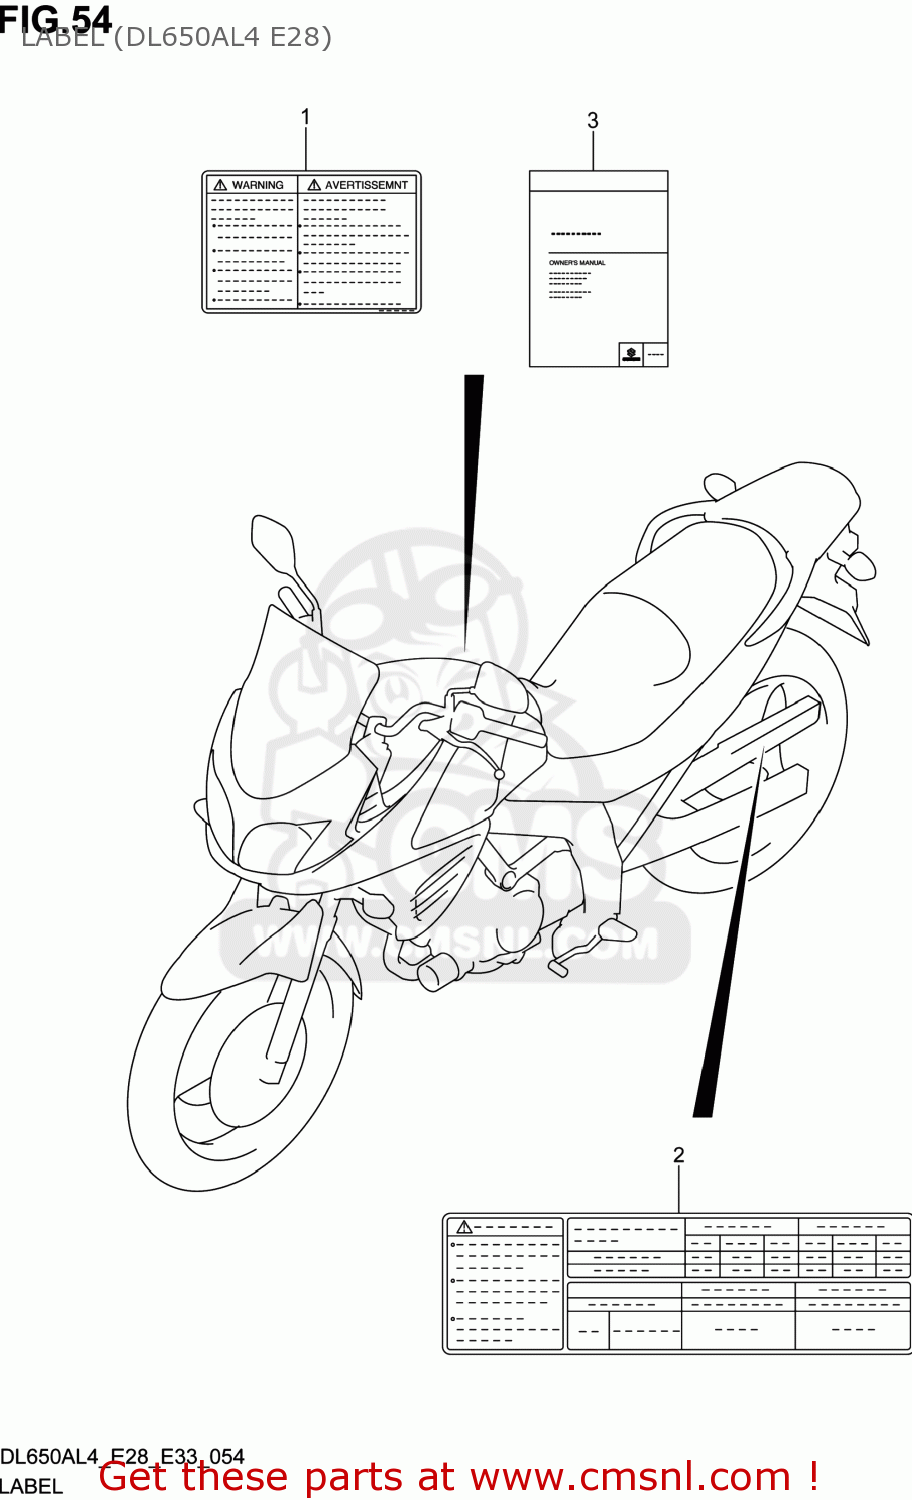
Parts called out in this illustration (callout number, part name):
1	LABEL,GENERAL WARNING
2	LABEL,TIRE INFORMATION
3	MANUAL,OWNER'S
